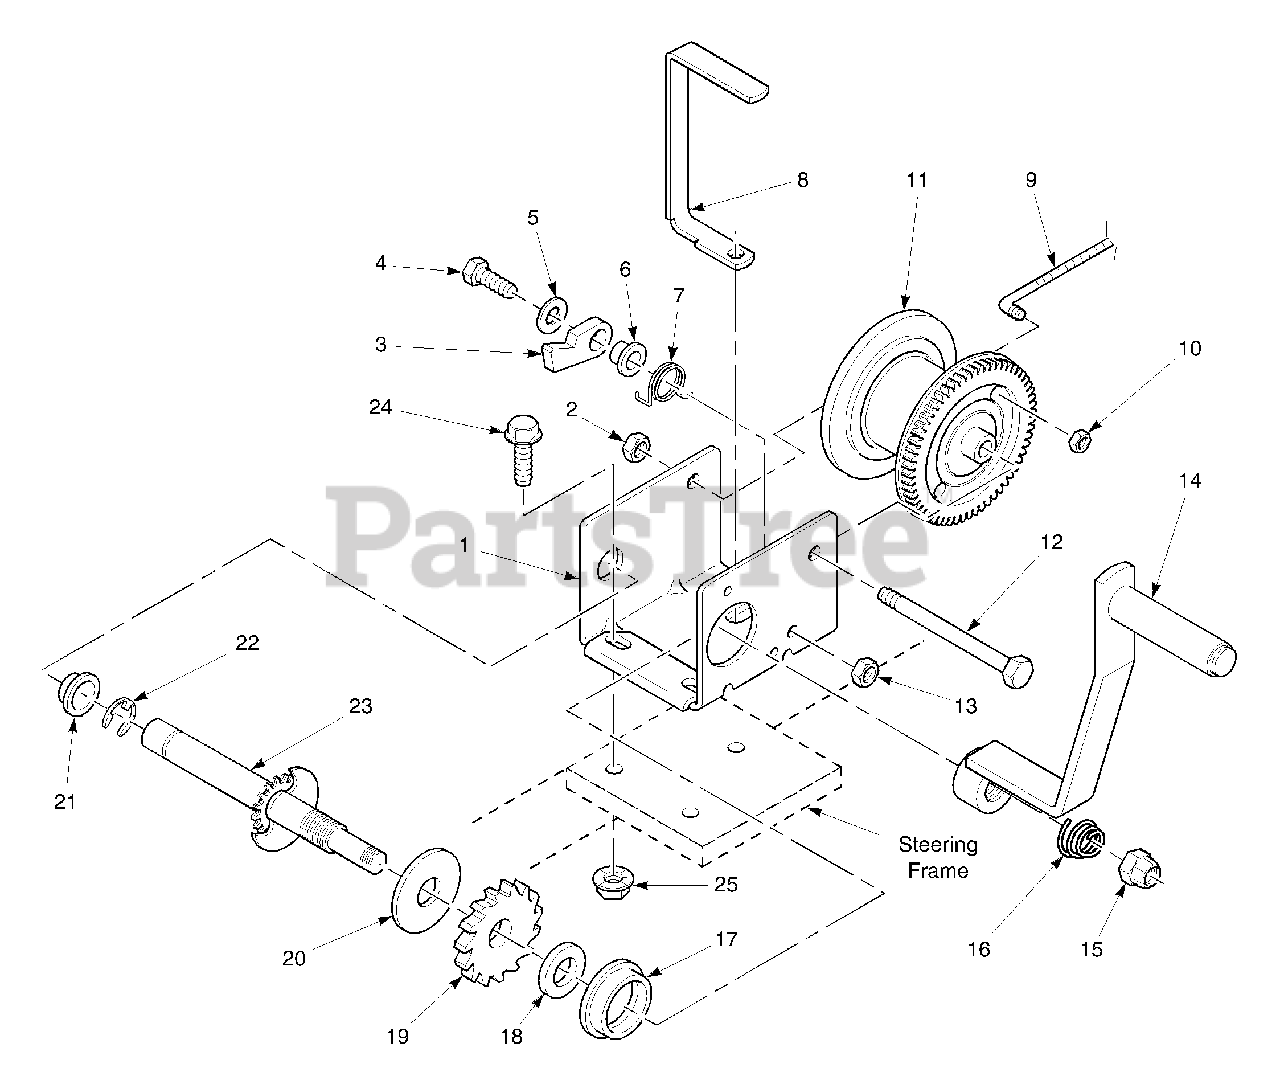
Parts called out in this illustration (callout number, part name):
1	Winch Assembly
2	Locknut, 7/16-14
3	Ratchet Pawl
4	Ratchet Bolt
5	Flatwasher
6	Ratchet Spacer
7	Ratchet Spring
8	Cable Guide
9	Winch Cable Assembly
10	Hex Locknut, 1/4-28
11	Winch Reel
12	Reel Shaft
13	Hex Locknut, 3/8-16
14	Winch Handle
15	Handle Nut
16	Handle Spring
17	Shaft Bushing
18	Pressure Washer
19	Ratchet Wheel
20	Pressure Plate
21	Shaft Bushing
22	E-Ring
23	Drive Shaft
24	Serr. Flg. HH Capscrew, 3/8-16 x 1"
25	Serr. Flg. HH Nut, 3/8-16
